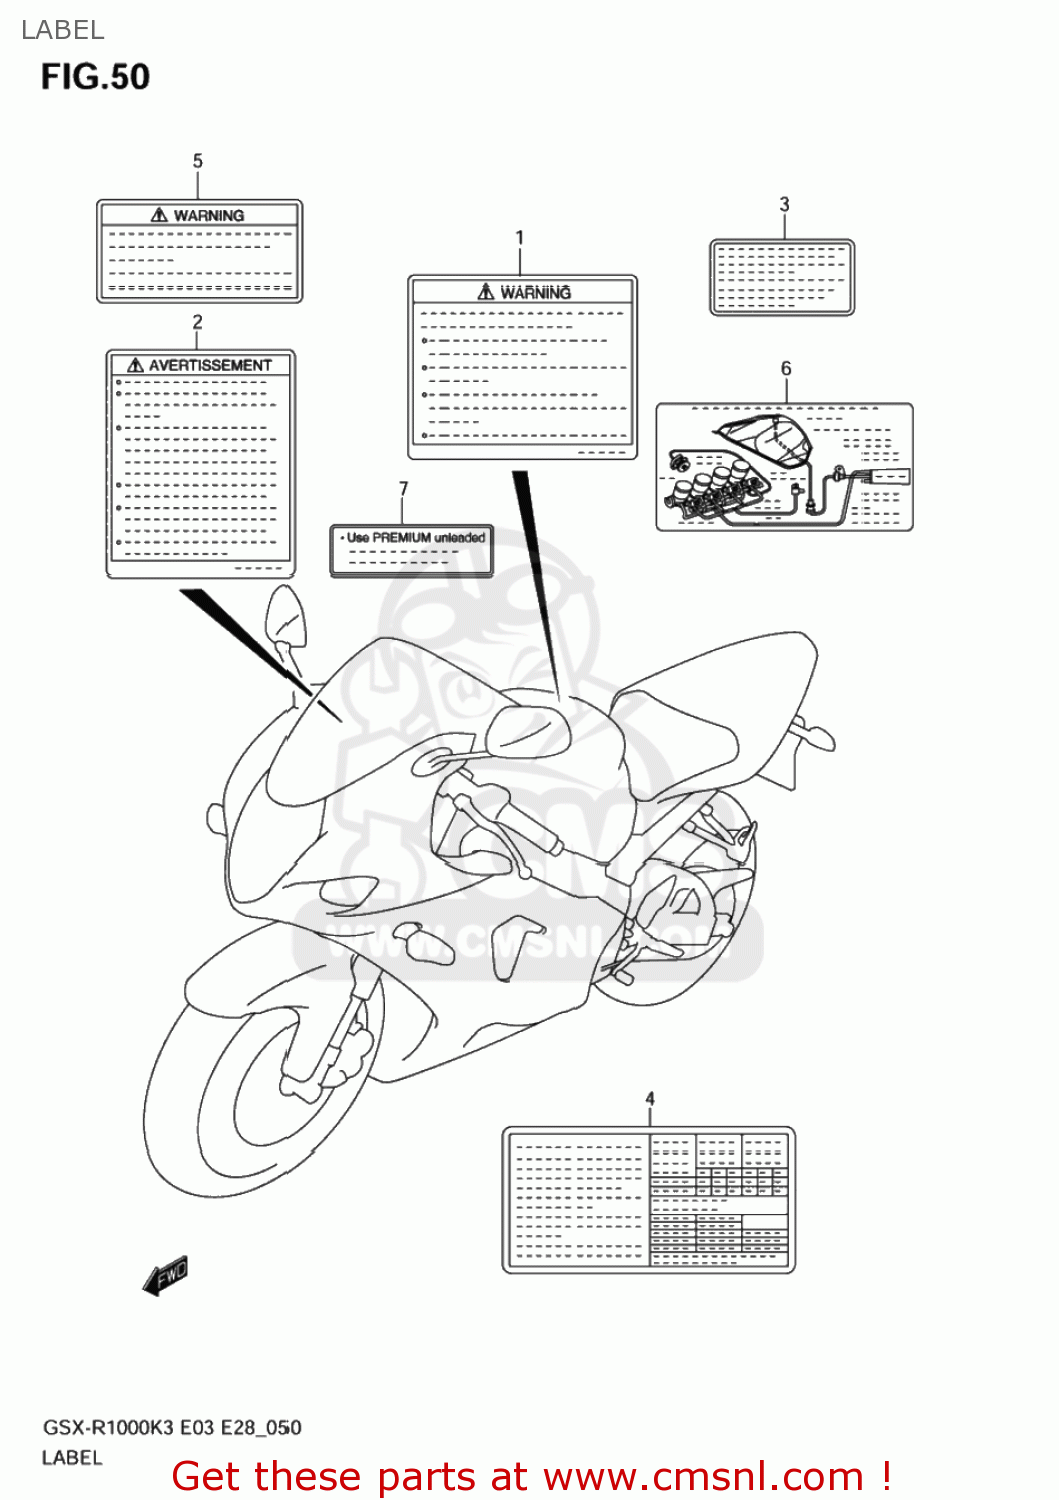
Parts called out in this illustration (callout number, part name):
1	LABEL,GENERAL WARNING
2	LABEL,SCREEN
3	LABEL,MANUAL NOTICE
4	LABEL,TIRE INFORMATION
5	LABEL,WARNING STEERING
6	LABEL,VACUUM HOSE ROUTING
7	LABEL,FUEL INFORMATION
8	MANUAL,OWNER'S
